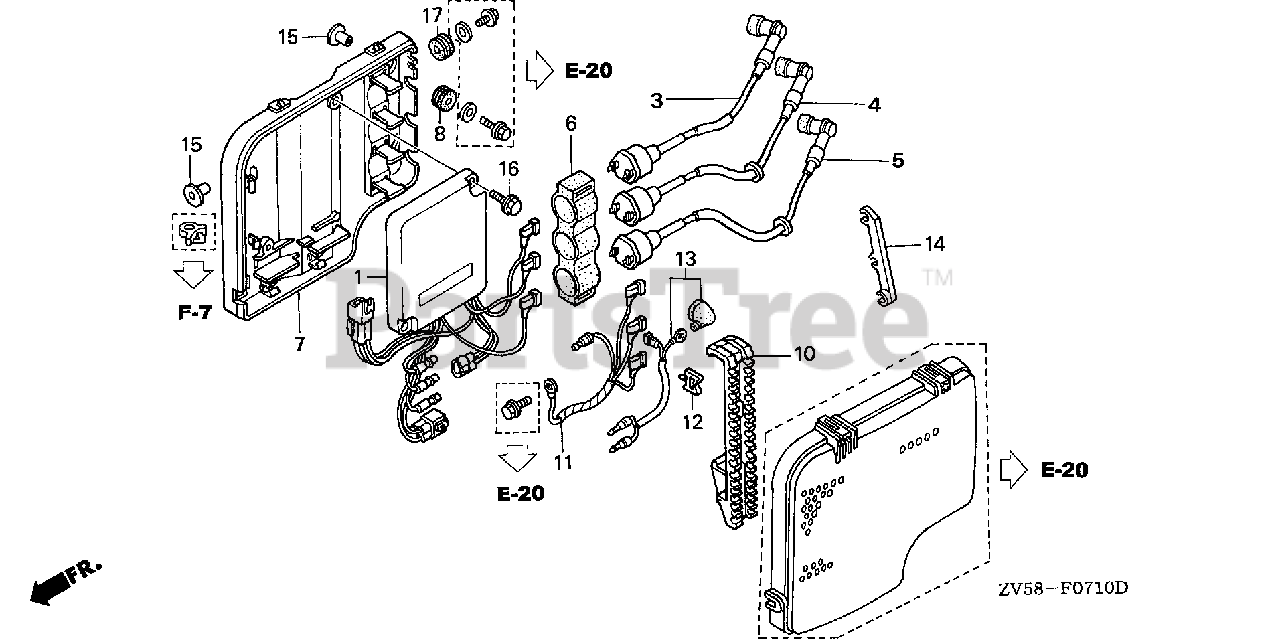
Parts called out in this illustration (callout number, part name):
1	MODULE, IGNITION CONTROL (CDI)
3	COIL, IGNITION (1)
4	COIL, IGNITION (2)
5	COIL, IGNITION (3)
6	SUSPENSION, IGNITION COIL
7	CASE, IGNITION CONTROL MODULE (CDI)
8	GROMMET, MODULE IGNITION CONTROL CASE (CDI)(B)
10	BRACKET, CONNECTOR (A)
11	WIRE ASSY., GROUND
12	CLIP, TURN SIGNAL WIRE
13	WIRE, SWITCH
14	CLIP, HIGH TENSION CORD
15	COLLAR, MODULE IGNITION CONTROL CASE (CDI)
16	BOLT, FLANGE (6X20)
17	GROMMET, CASE (LOWER)
